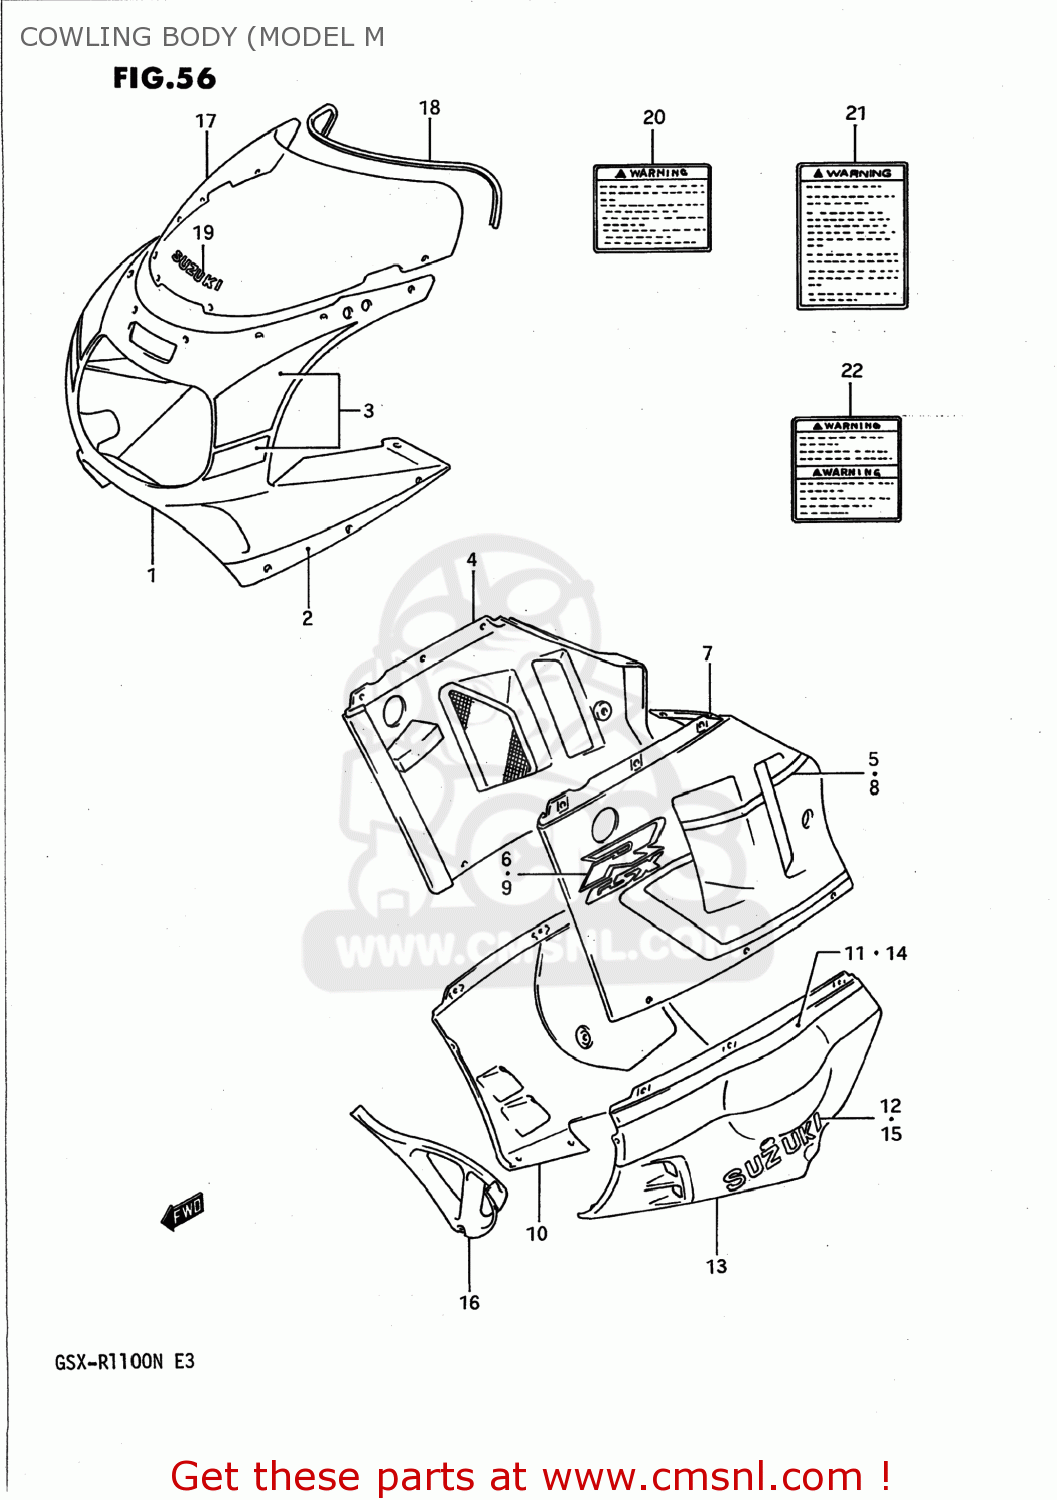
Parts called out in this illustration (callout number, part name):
1	BODY ASSY,COWLING
2	TAPE SET,COWLING
3	TAPE SET,COWLING,UPPER
4	COVER COMP,COWLING SIDE,RIGHT
5	TAPE SET,COWL SIDE STRIPE,R
6	EMBLEM,COWLING SIDE
7	COVER COMP,COWLING SIDE,LEFT
8	TAPE SET,COWL SIDE STRIPE,L
9	EMBLEM,COWLING SIDE
10	COWLING COMP,UNDER,RIGHT
11	TAPE,COWLING,UNDER STRIPE
12	EMBLEM,SUZUKI
13	COWLING,UNDER,L
14	TAPE,COWLING,UNDER STRIPE
15	EMBLEM,SUZUKI
16	COWLING,UNDER CTR
17	SCREEN SET,WIND
18	MOLDING
19	EMBLEM,SUZUKI(WHITE)
20	LABEL
21	LABEL (WARNING SCREEN)
22	LABEL (WARNING)
